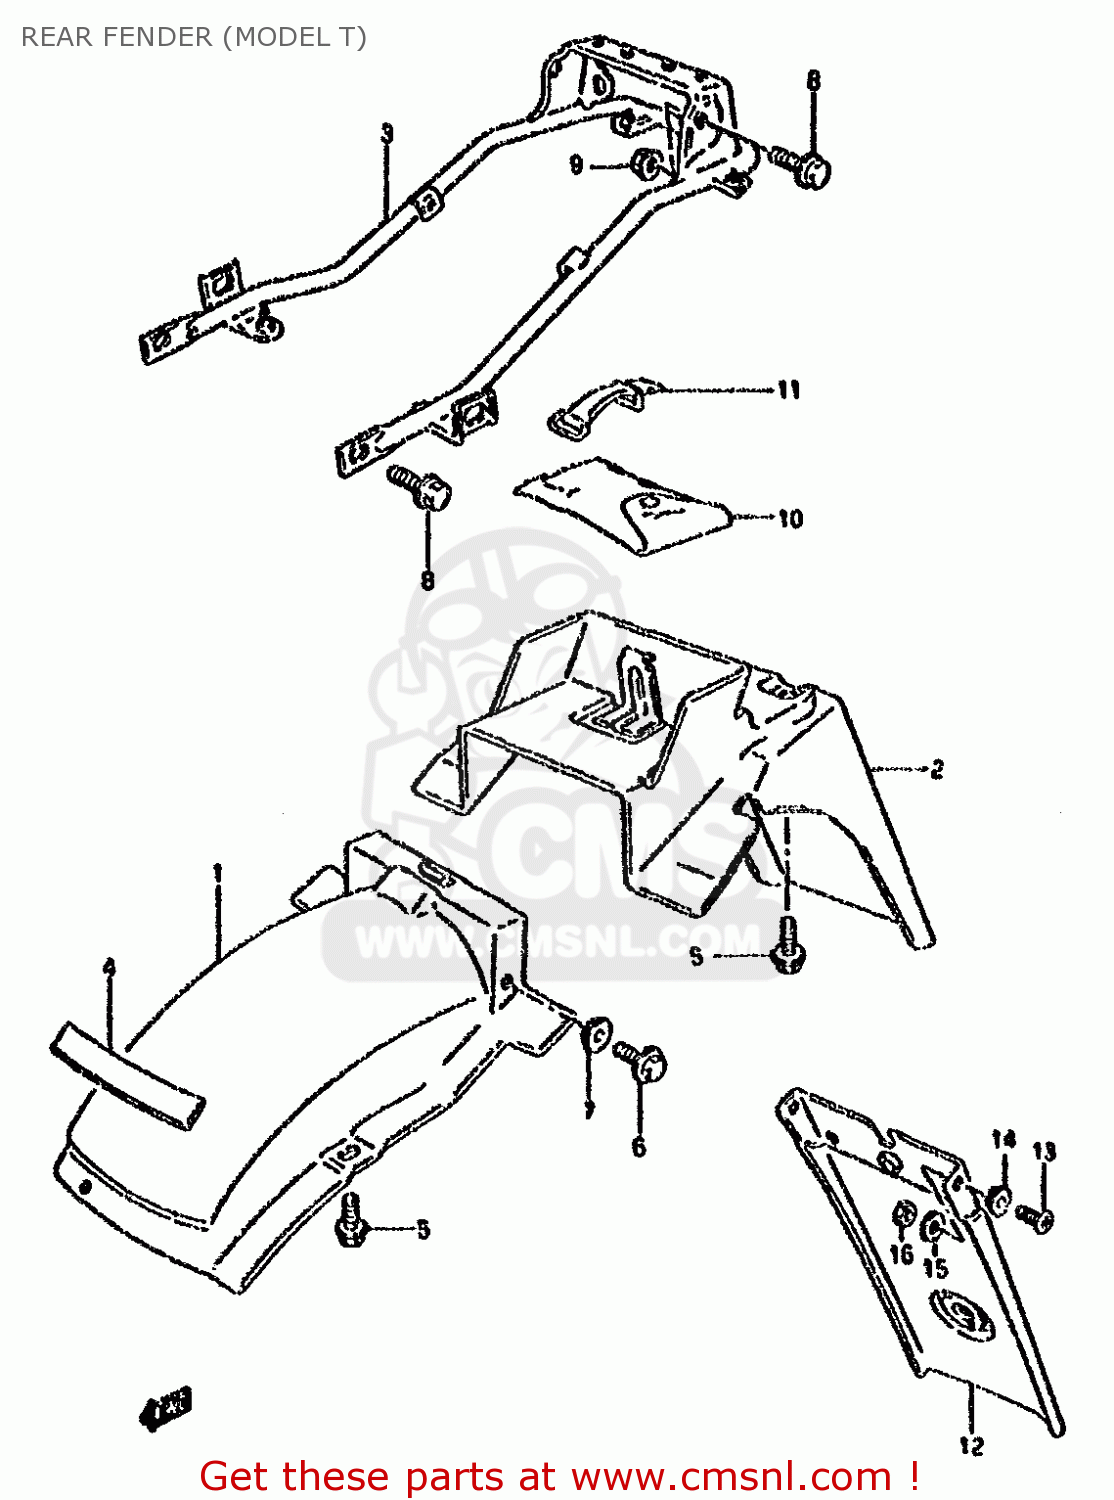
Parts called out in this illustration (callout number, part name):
1	BODY, REAR FENDER FRONT
2	BODY,RR FENDER RR
3	REINFORCEMENT, REAR FENDER
4	CUSHION, REAR FENDER
5	BOLT
6	BOLT(6X16)
7	WASHER
8	BOLT
9	NUT
10	TOOL ASSY
11	BAND
12	MUDGUARD,RR FENDER
13	SCREW
14	WASHER
15	WASHER
16	NUT
